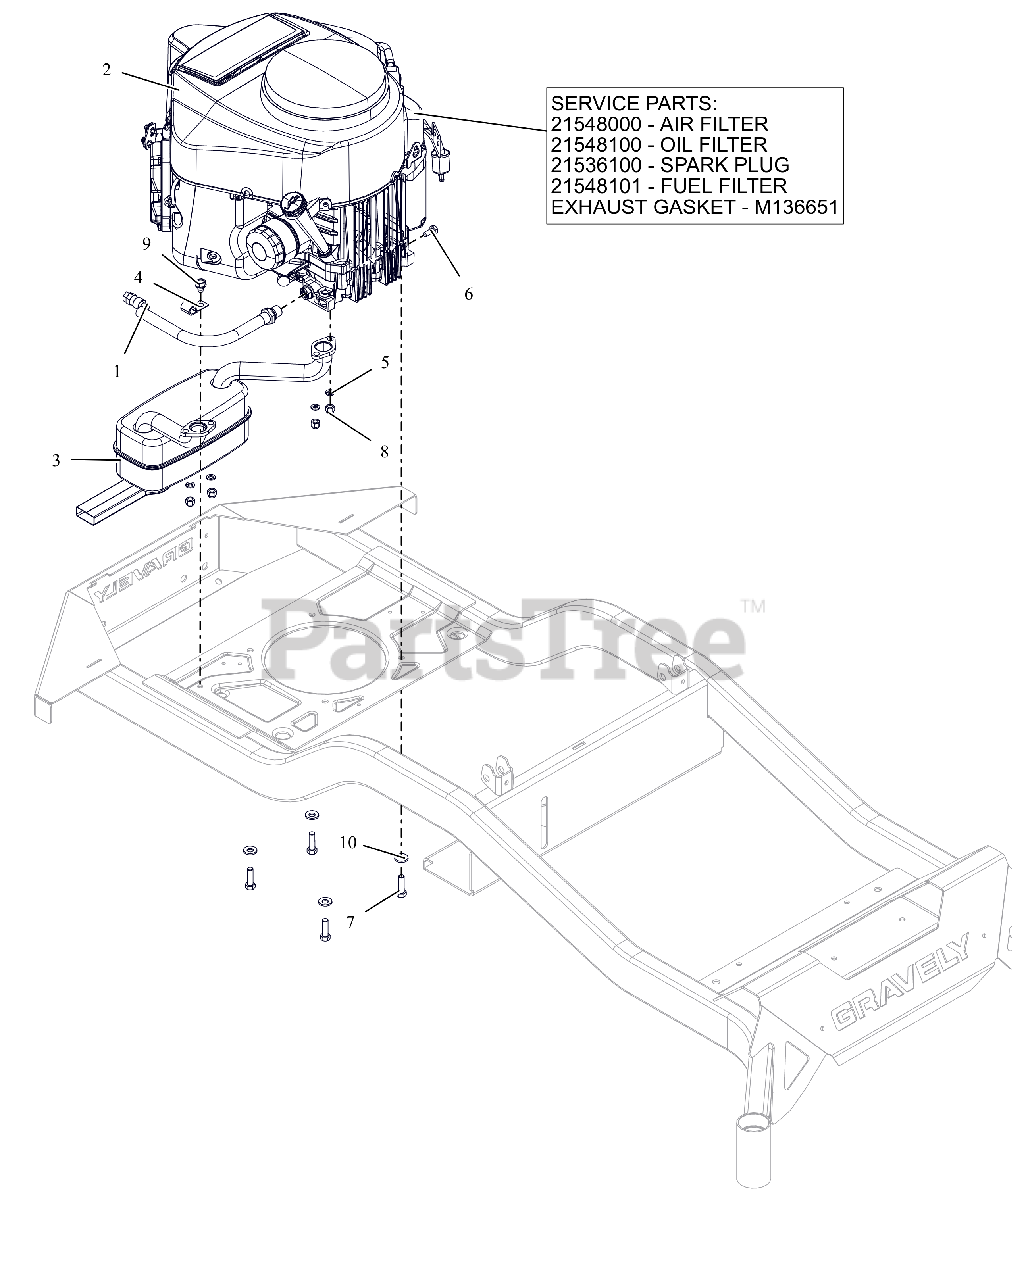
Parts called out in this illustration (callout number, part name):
1	HOSE, OIL DRAIN
2	ENGINE, KAWASAKI FR691 23HP
2	AIR FILTER, KAWASAKI FR
2	OIL FILTER, KAWASAKI FR
2	PLUG, SPARK
2	FUEL FILTER-KAWASAKI FR
2	GASKET, MUFFLER #
3	MUFFLER, KAWASAKI
5	WSHR,LK-REG .312X.078 ZCC
6	BLT, HEX M8-1.25X20 G8.8 ZCC
7	BLT, HEX .38-16X1.25 G5 ZCC NT
8	NUT,NYL M8-1.25 G8.8 ZCC
9	SCR,TAP .375-16X.50 HWH TR ZCC
10	WASHER, 3/8" SPRING DISC
